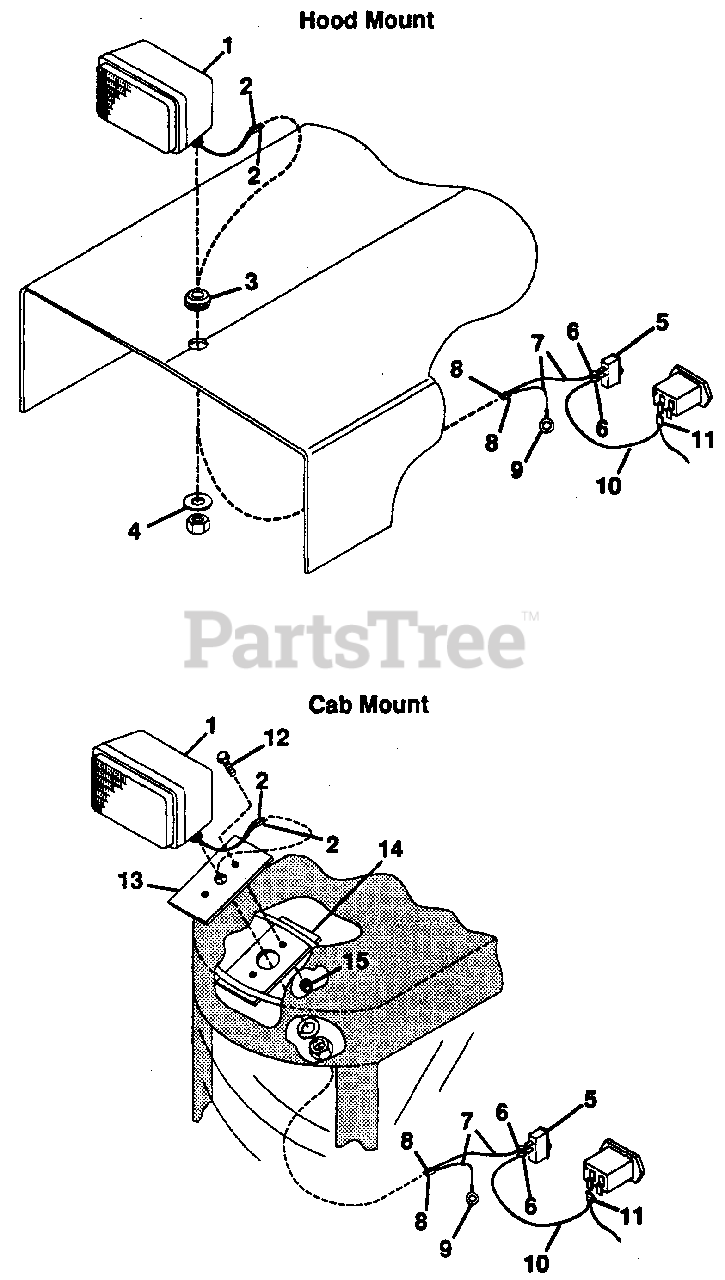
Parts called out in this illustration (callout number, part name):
1	Headlamp, 3x5x Halogen
2	Terminal, Male
3	Grommet
4	Washer, Flat .531x1.000x.063
5	Switch, Light
6	Terminal, Female 1-Wire 16 Ga.
7	Wire, #1
8	Terminal, Female
9	Terminal, Ring Tongue
10	Wire, #2
11	Terminal, Female 2-Wire
12	Bolt, Hex 1/4-20x1.00
13	Bracket, Cab Top
14	Bracket, Cab Bottom
15	Nut, Lock 1/4-20
NS	Tie, Cable
